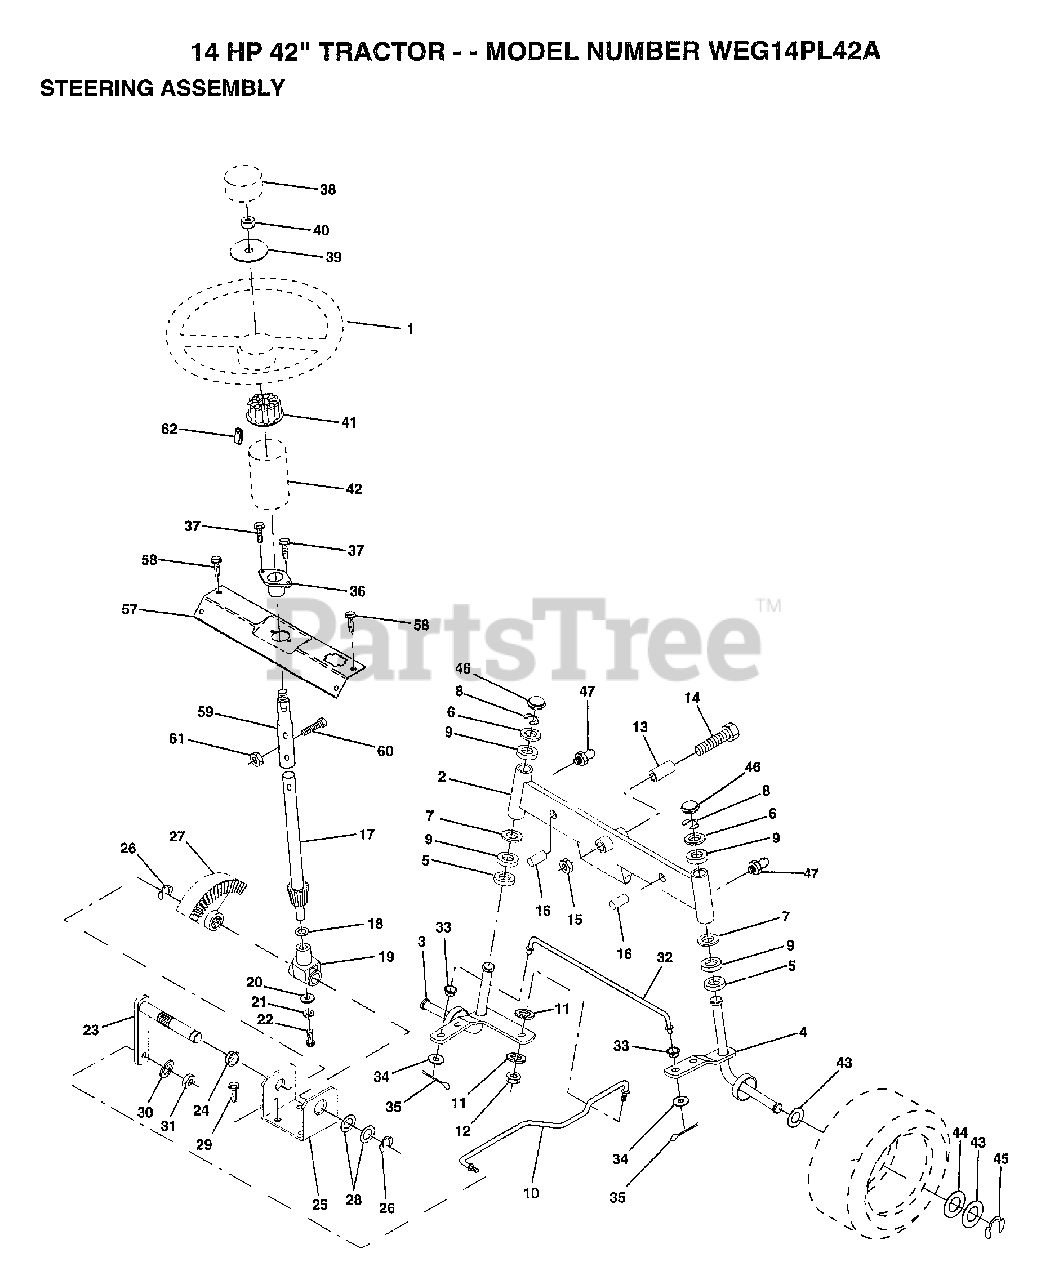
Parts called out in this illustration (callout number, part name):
2	AXLE ASM FRONT
3	SPINDLE LH
4	SPINDLE RH
5	WASHER .T
6	WASHER
7	WASHER
8	RING
9	COL. SRTG. BEAR.
11	LOCKWASHER
13	BEARING
14	BOLT HEX 5/8-11
15	"NUT-LOC,FLANGE LT"
16	AXLE PIN
17	SHAFT ASM STEERIN
18	THRUST WASHER
19	SUPPORT.SHAFT
21	LOCKWASHER
22	"SCREW,SPECIAL"
24	NYLINER T
25	"BRKT,STEERING"
26	RING
27	GEAR SECTOR
28	WASHER .T
29	SCREW
30	LOCKWASHER
32	TIE ROD
33	BUSHING.DRAGLINK
34	WASHER
35	COTTER PIN
38	ST WHL INSERT CAP
39	WASHER T
40	GRIPCO NUT
41	ADAPTER-WHEEL LT
42	BOOT SHAFT STEER
43	WASHER
44	WASHER
45	RING
46	CAP
47	ZERK M
57	SUPPORT SHAFT STR
58	SCREW HEX CRT
59	SHAFT EXT STEER
60	BOLT
61	NUT
62	CLIP TINNERMAN
